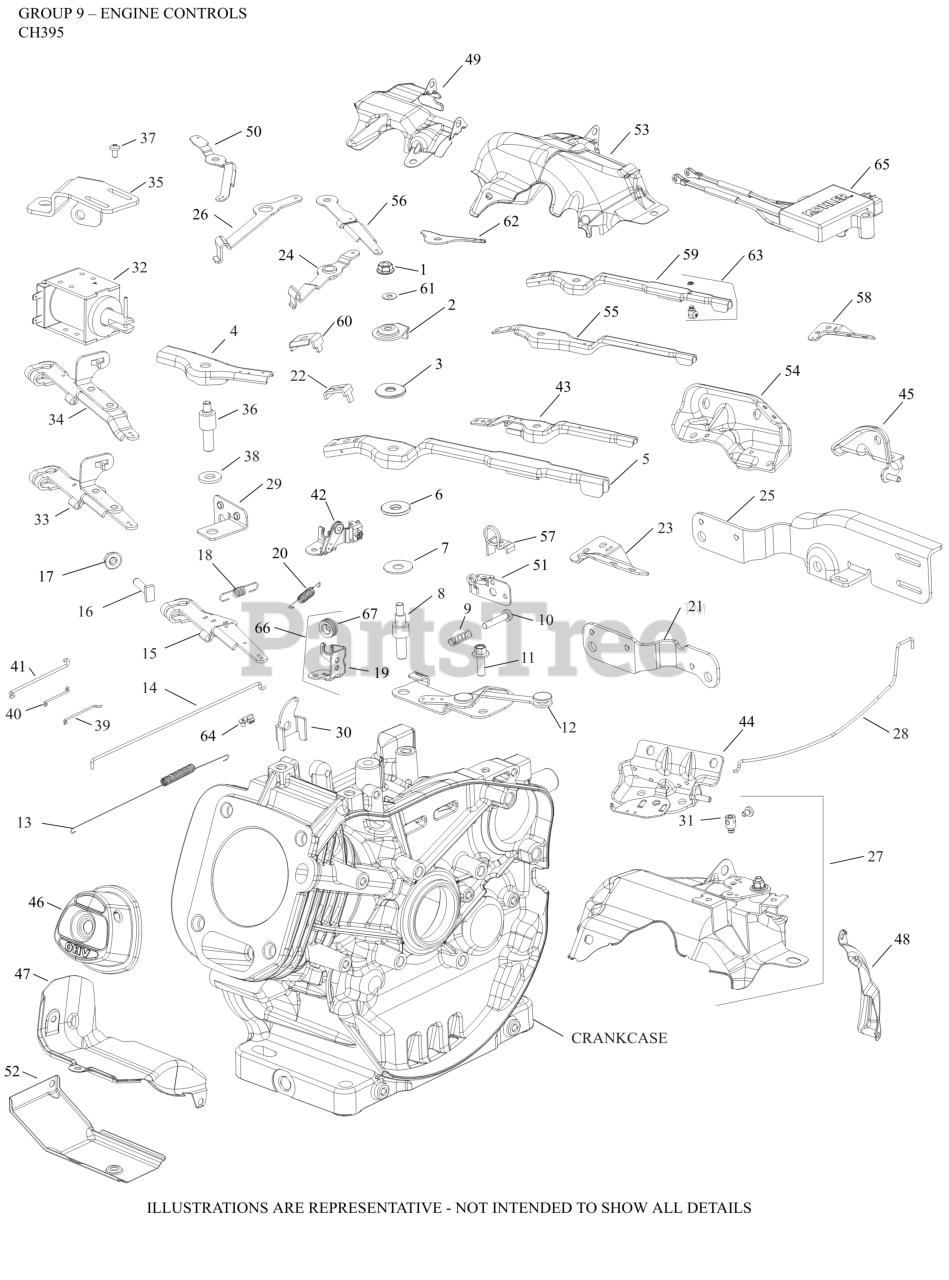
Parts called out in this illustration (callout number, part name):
1	NUT, HEX FLANGE LOCK (M6)
9	SPRING, COMPRESSION
10	SCREW, SPEED ADJUSTING
11	SCREW, M6 X18
13	SPRING, LINKAGE
14	LINKAGE, GOVERNOR
15	KIT, GOVERNOR LEVER
16	SCREW, RECTANGLE HEAD (M6)
17	NUT, HEX FLANGE (M6) - USE 14 100 16-S
18	SPRING, GOVERNOR
29	BRACKET, CONTROL
36	STUD, CONTROL LEVER
